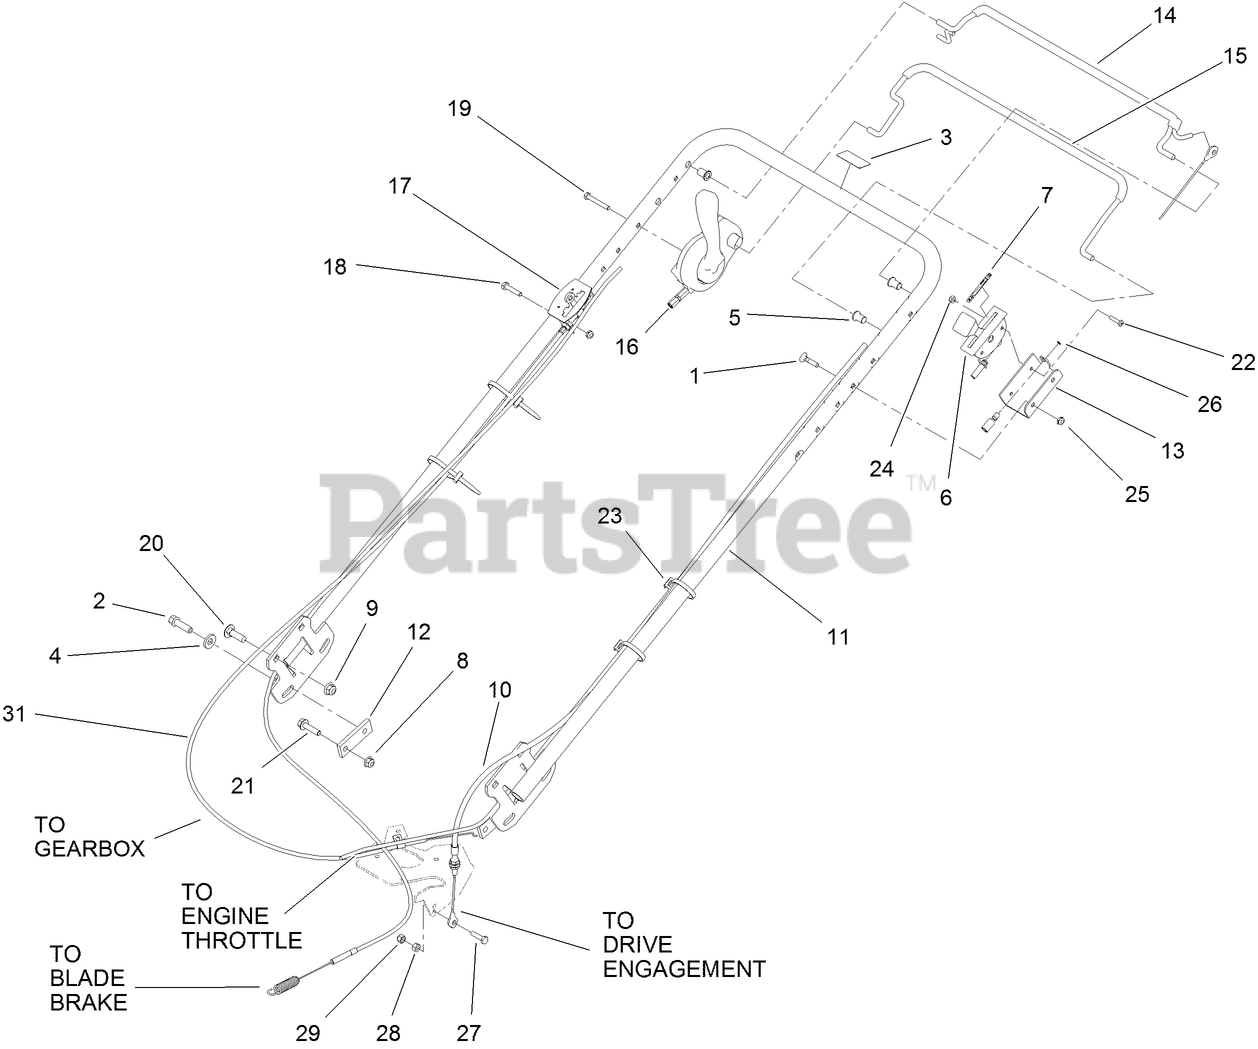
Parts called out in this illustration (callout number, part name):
1	BOLT-HANDLE
2	SCREW-TAPTITE
3	DECAL-PROTECTION, EAR
4	WASHER-BELLEVILLE
5	BUSHING
6	CONTROL-THROTTLE
7	DECAL-THROTTLE / CHOKE
8	NUT-HF, NI
9	NUT-HF, NI
10	CABLE-TRACTION
12	NUT-HANDLE
13	BRACKET-CONTROL
14	BAIL-TRACTION
15	BAIL-BBC (WITH GRIP)
16	CONTROL-BBC
17	CONTROL-SHIFT
18	SCREW-HH
19	SCREW-HH
20	BOLT-CARR
21	SCREW-HHF
22	SCREW-PPH
23	TIE-CABLE
24	NUT-LOCK, NI
25	NUT-LOCK, NI
26	E-RING
27	SCREW-HH
28	NUT-HEX
29	NUT-LOCK, NI
31	CABLE-SHIFTER
